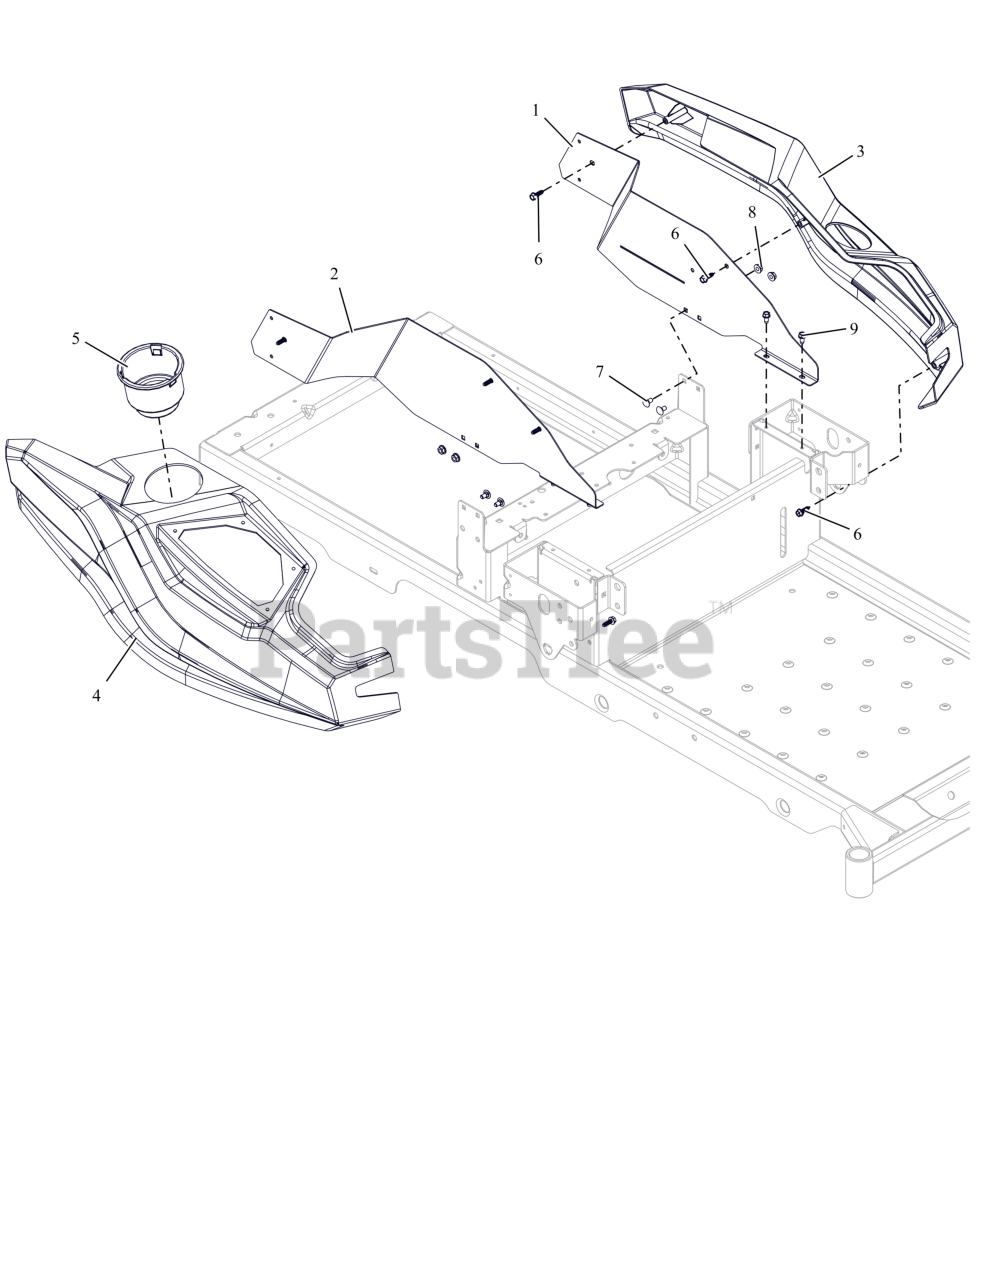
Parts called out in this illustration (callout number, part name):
1	BRKT, FENDER MOUNTING LH (ORANGE)
2	BRKT, FENDER MOUNTING RH (ORANGE)
3	KIT-FENDER WITH DECAL
4	FENDER, RH - ZOOM
5	CUPHOLDER, SNAP-IN 3.75OD
6	SCR, PLASTITE .25-10X.75 ZCC
7	BLT, RHSN .25-20X.500 G5 ZCC
8	NUT-LK-CTR-FLG .25-20 ZC120
9	SCR-TAP .25-20X.50 HWH ZCC
